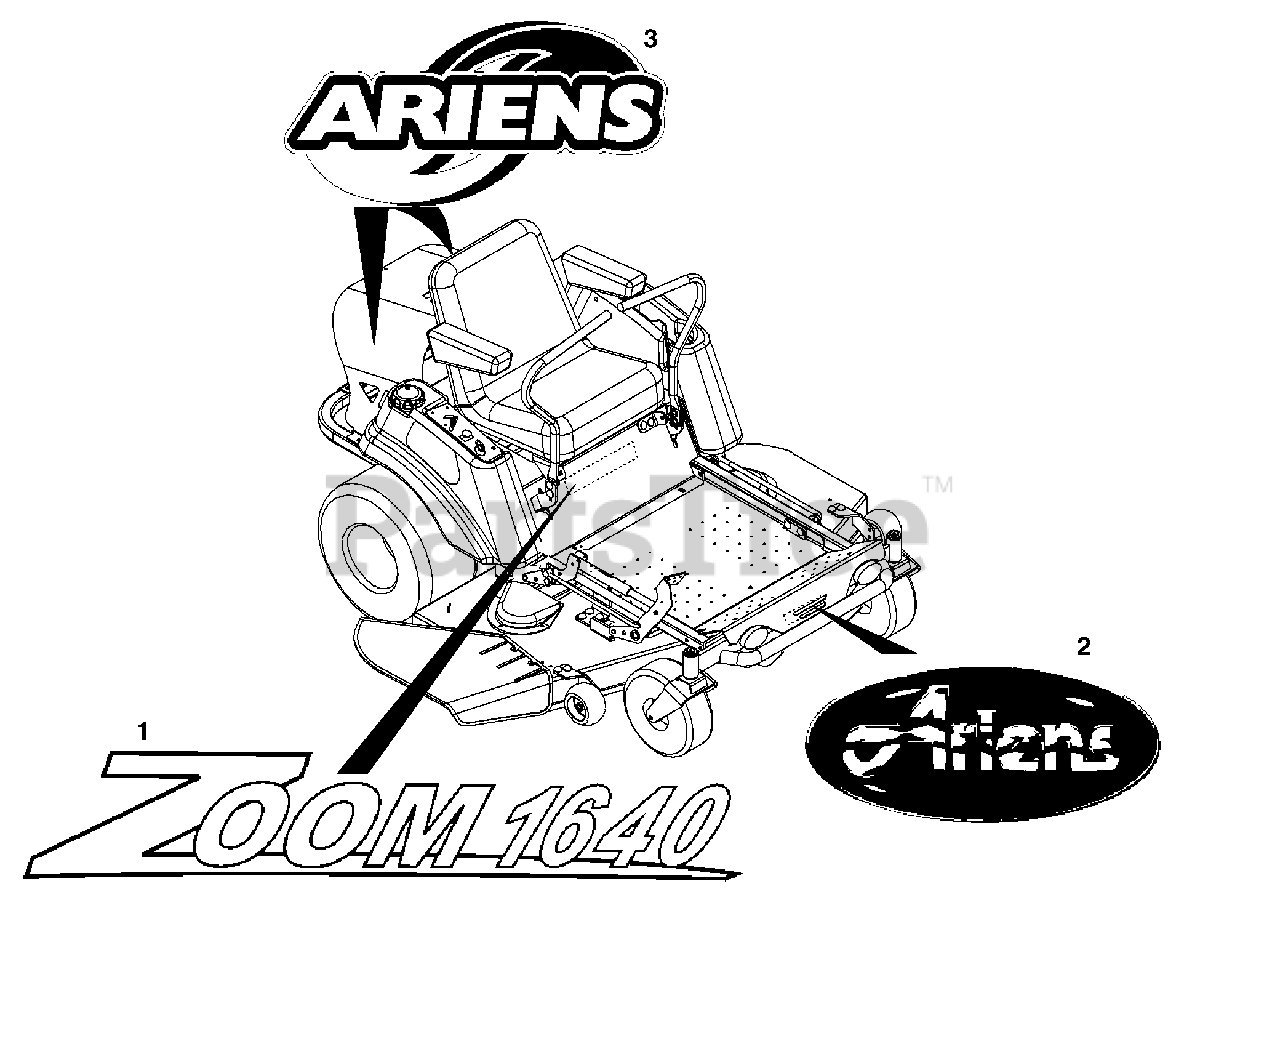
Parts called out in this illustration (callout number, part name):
1	DECAL ZOOM 1640
2	DECAL-ARIENS JEWEL
3	DECAL ZOOM HOOD
